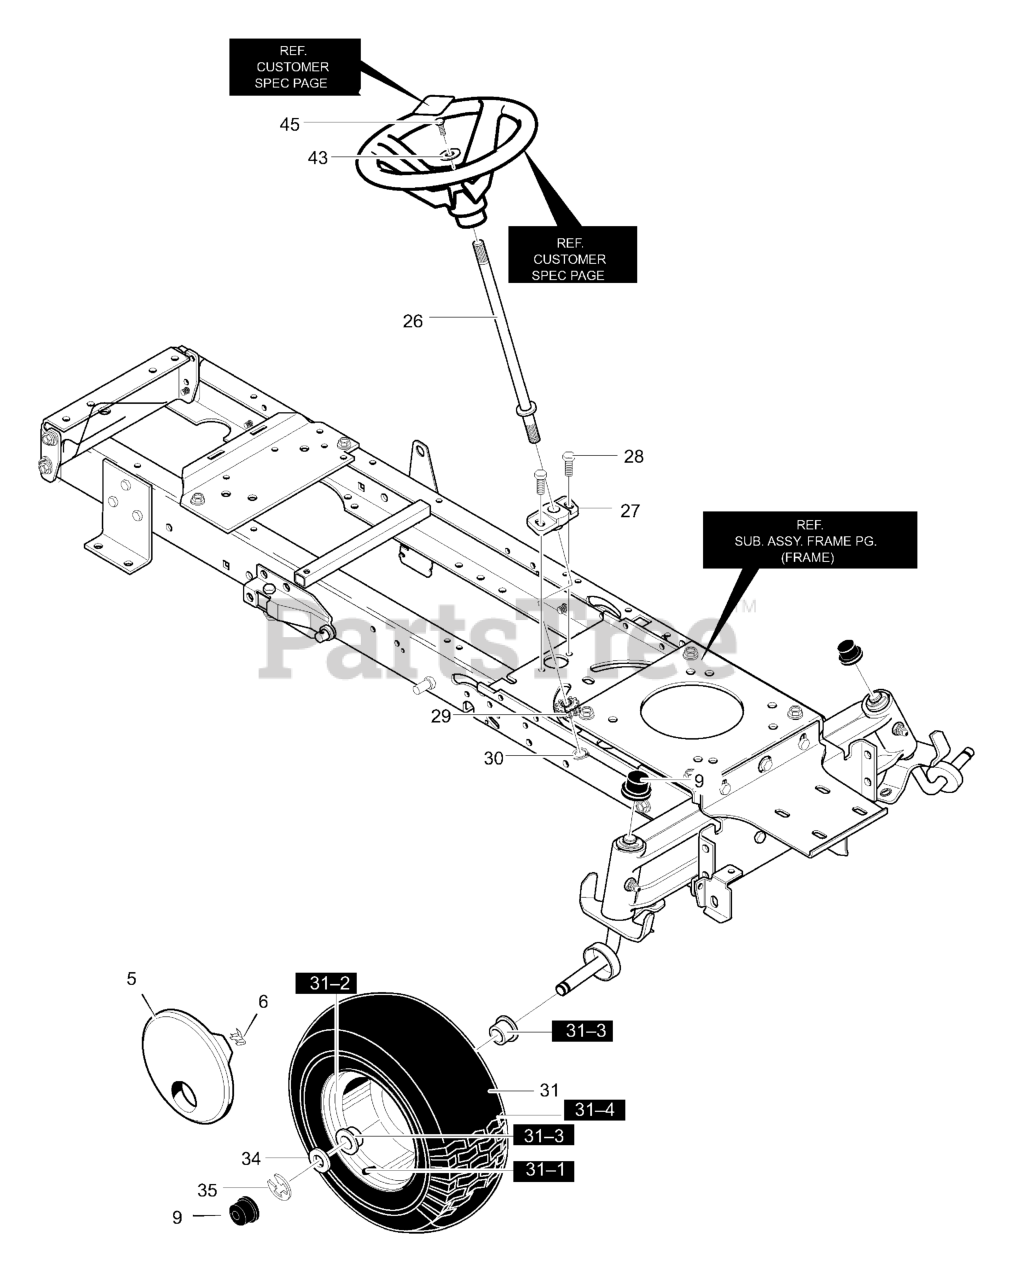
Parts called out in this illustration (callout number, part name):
5	HUB CAP, 6"
6	RETAINER
9	DUST HUB CAP
26	SHAFT, STEERING
27	BEARING-LOWER
28	SCREW, 5/16-18 x 0.75
29	GEAR, PINION
30	RETAINING RING
31	TIRE & RIM
31-1	VALVE STEM
31-3	BEARING
34	FLATWASHER
43	FLAT WASHER
45	SCREW 1/4-20X.75
